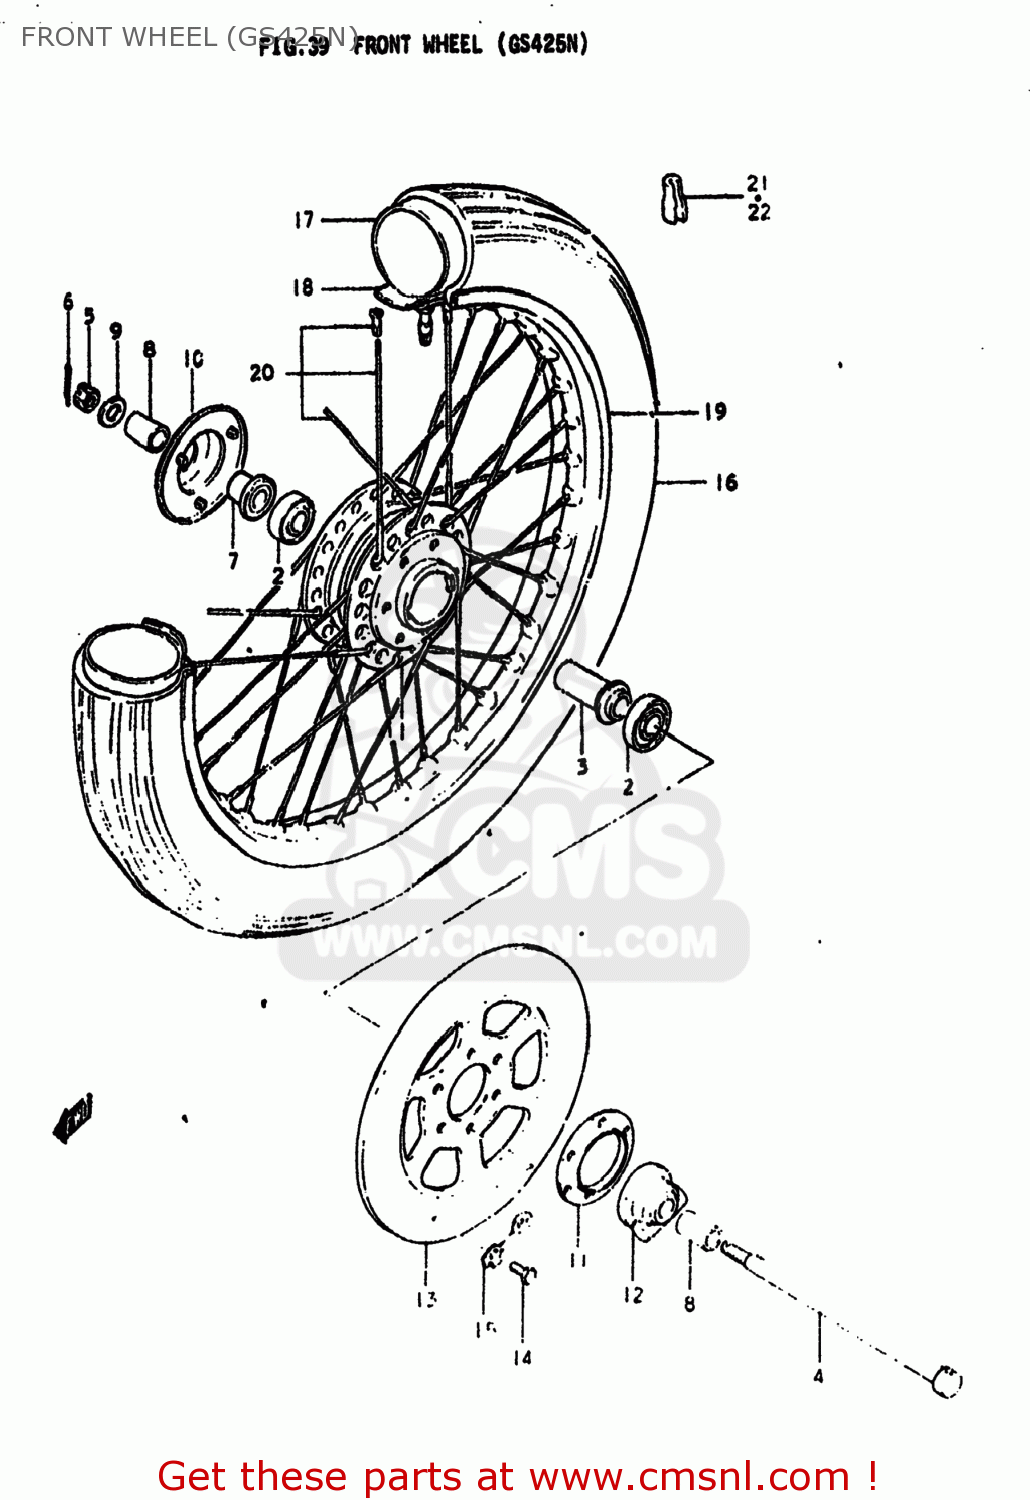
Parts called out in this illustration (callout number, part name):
1	DRUM,FRONT HUB
2	BEARING
3	SPACER,FR HUB BEARING
4	AXLE,FRONT
5	NUT 12MM
6	COTTER PIN
7	SPACER,FR AXLE,R
8	SPACER(15X22X30)
9	WASHER
10	COVER,FR HUB,R
11	DUST SEAL,SPEEDOMETER GEAR BOX
12	BOX ASSY,SPEEDOMETER GEAR
13	DISC,REAR BRAKE
14	BOLT(8X25)
15	WASHER
16	TIRE,FRONT
17	TUBE,INNER
18	PROTECTOR,WHEEL,INNER
19	RIM,FR WHEEL
20	SPOKE SET,FRONT
21	BALANCER,WHEEL (B)
22	BALANCER,WHEEL (30G)
